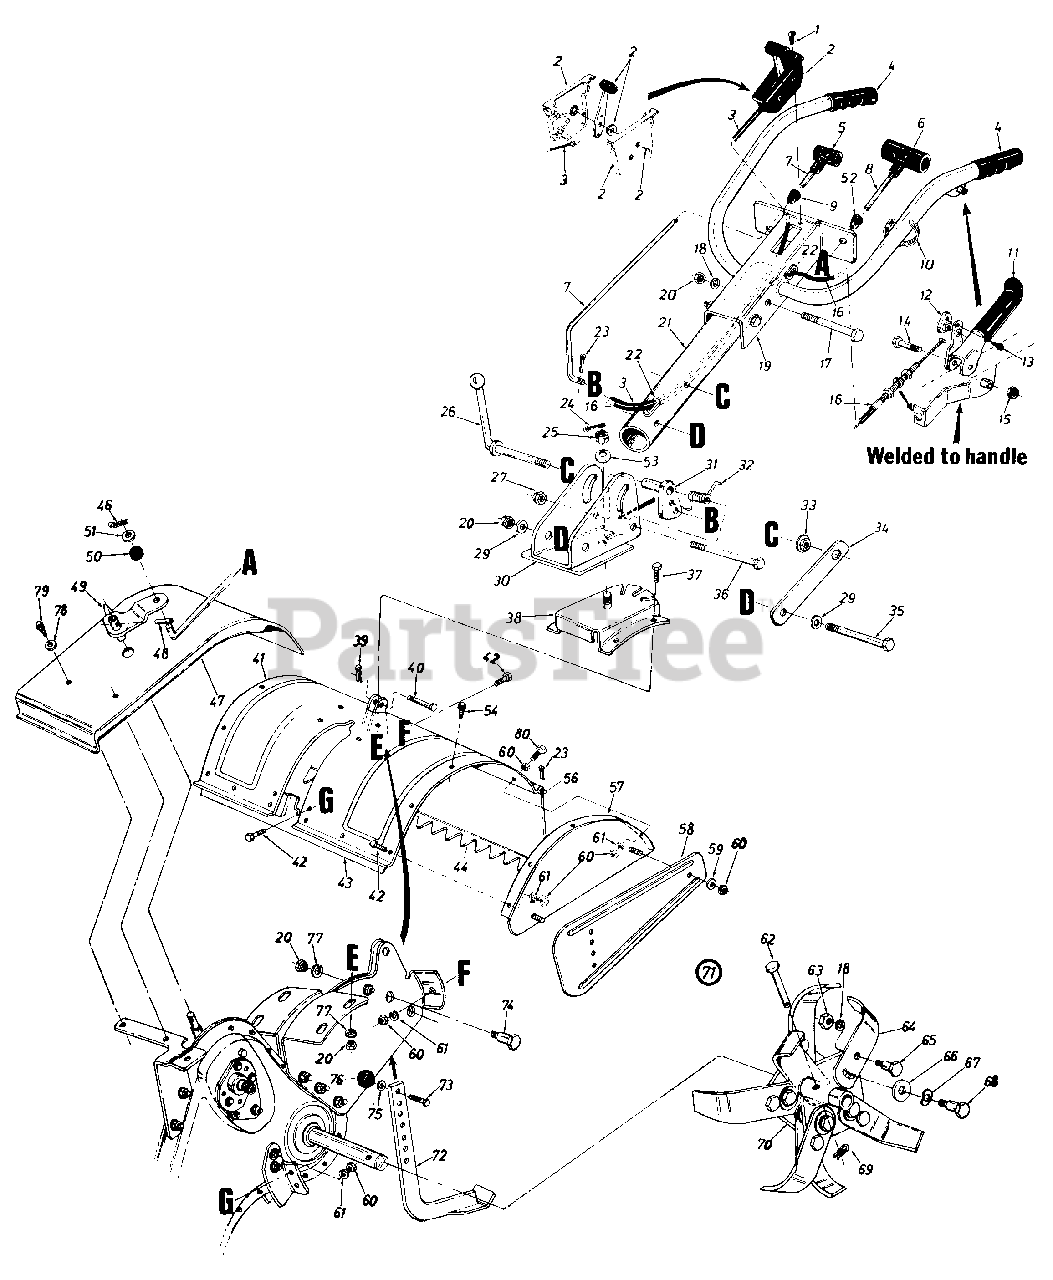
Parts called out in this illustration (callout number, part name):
1	Truss Mach. AB-Tap. Scr. #10 x .50" Lg.
2	Throttle Control Box Ass'y.
3	Throttle Control Wire
4	Handle Grip
5	Small "T" Knob
6	Large"T" Knob
7	Clutch Rod
8	Control Rod 37" Lg.
9	Snap On Bushing 3/8" Dia.
10	Cable Tie-Self Clinching
11	Clutch Grip Ass'y. L.H.
12	Barrel Cable Hold Down
13	Hex B-Tap Scr. #10 x .44" Lg.
14	Hex Bolt 3/8-16 x 2.0" Lg.
15	Hex Cent. L-Nut 3/8-16 Thd.
16	Clutch Control Cable 53" Lg.
17	Hex Bolt 3/8-16 x 3.00" Lg.
18	L-Wash. 3/8" I.D. H.D.
23	Cotter Pin 3/32" Dia. x .75" Lg.
24	Cotter Pin 3/32" Dia. x 1.25" Lg.
25	I lex Slotted Nut 5/8-18 Thd.
26	Handle Adj. Crank
27	Hex Cent. L-Nut 3/8-16 Thd.
29	Bell-Wash. .4" I.D. x .87" O.D.
30	HandlePivot Bracket
31	Positioner Crank Ass'y.
32	Spring Handle Adj.
33	Hex Flange Nut 3/8-24 Thd.
34	Bracket Hex Nut Retainer
35	Hex Bolt 3/8-16 x 3.25" Lg.
36	Hex Bolt 3/8-16 x 3.00" Lg. Gr. 8
37	Hex Bolt 3/8-16 x .75" Lg.
40	Clevis Pin .375" Dia.
43	Bracket Reinforcement 18"
46	Intern. Cotter Pin 5/16" Dia.
49	Shifting Crank Ass'y.
50	Rubber Washer .33" I.D.
51	Fl-Wash. .4" I.D. x 1.25" O.D.
52	Snap On Bushing 1/2" Dia.
53	Bell-Wash. .63" I.D. x 1.25"
54	Hex Wash. Tap Scr.
56	Tiller Flap Rod
60	Hex Nut 5/16-18 Thd.
61	L-Wash. 5/16" I.D.
62	Clevis Pin .375" Dia.
63	Hex Nut 3/8-24 Thd.
65	Shld. Bolt 1/2" Dia. x .175
66	Fl-Wash. .51" I.D. x 1.50"
67	Bell-Wash. .515" I.D. x 1.14"
68	Shld. Bolt 1/2" Dia. x .320
69	Intern. Cotter Pin
73	Hex Bolt 3/8-16 x .75" Lg.
74	Shld. Bolt 1/2" I.D. x .62" Lg.
75	Fl-Wash. 3/8" I.D. x 5/8" O.D.
76	Ball Knob
77	L-Wash. 3/8" I.D.
78	Fl-Wash. .281" I.D. x .62"
79	Hex Wash. Self-Tap Scr. 1/4-20 X :50" Lg.
80	Hex Bolt 5/16-18 x 11/4" Lg.
